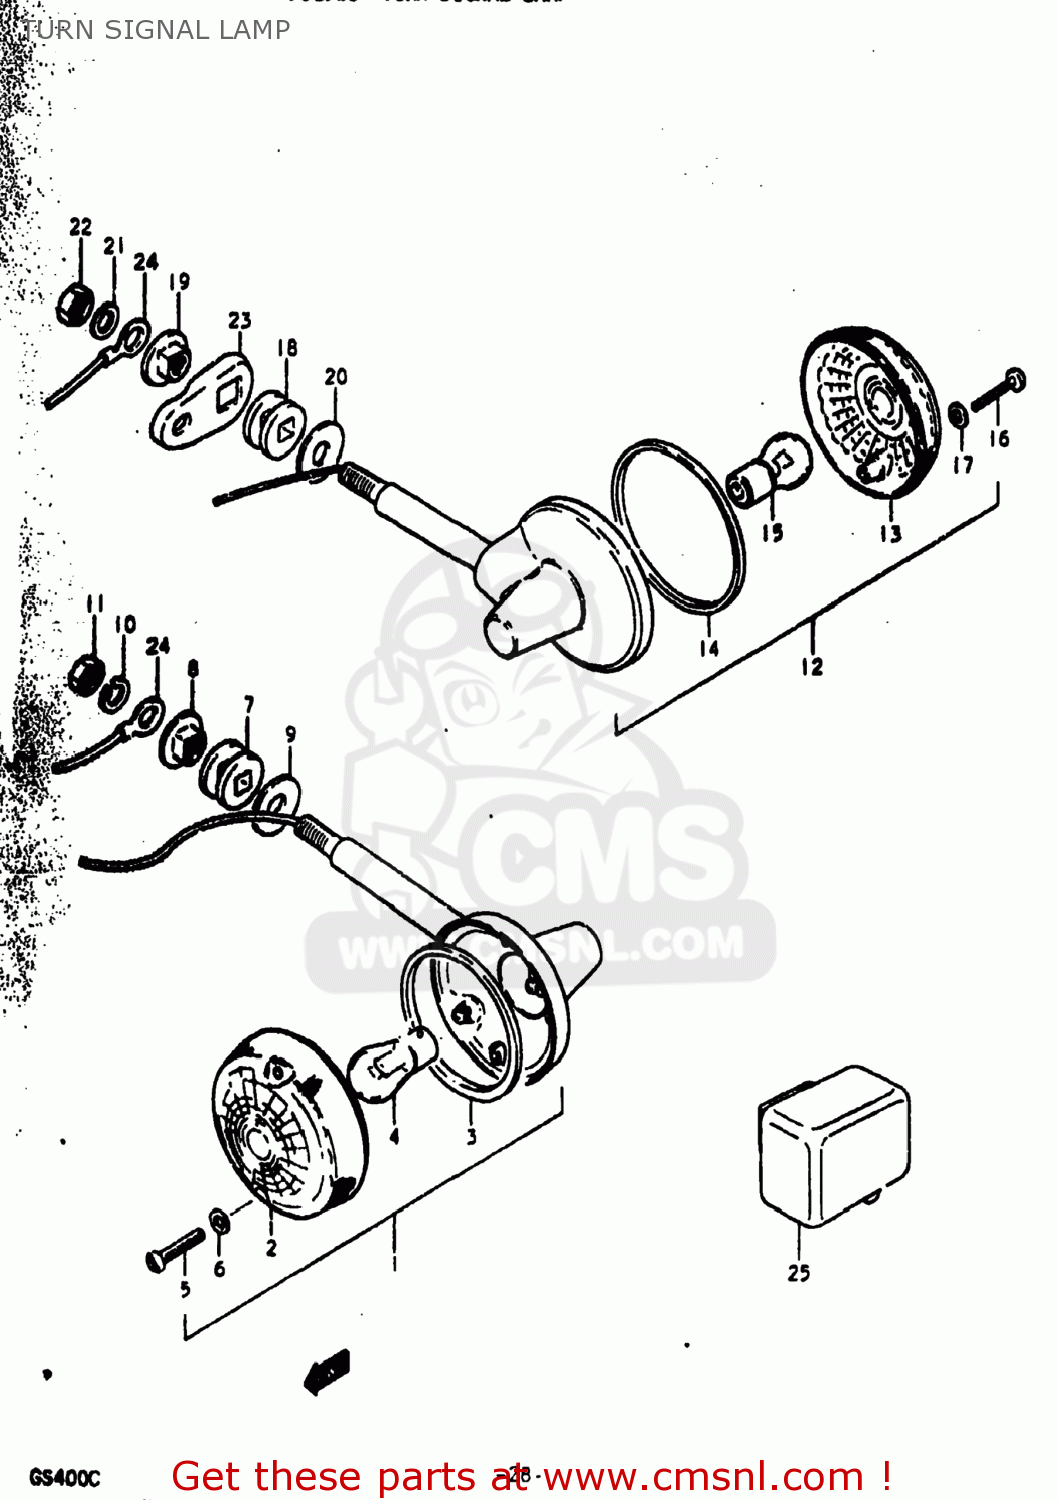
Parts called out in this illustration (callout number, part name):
1	LAMP ASSEMBLY,FRONT TURN SIGNAL
2	LENS
3	GASKET (NAS)
4	BULB(12V23W,STANLEY,A4577A)
5	SCREW
6	GASKET (NAS)
7	CUSHION
8	SPACER,RR TURNSIGNAL LAMP
9	WASHER
10	LOCK WASHER
11	NUT
12	LAMP ASSEMBLY,REAR TURN SIGNAL
13	LENS
14	GASKET (NAS)
15	BULB(12V23W,STANLEY,A4577A)
16	SCREW
17	GASKET (NAS)
18	CUSHION
19	SPACER,RR TURNSIGNAL LAMP
20	WASHER
21	LOCK WASHER
22	NUT
23	BRACKET,TURN SIGNAL
24	WIRE
25	RELAY,TURN SIGNAL
